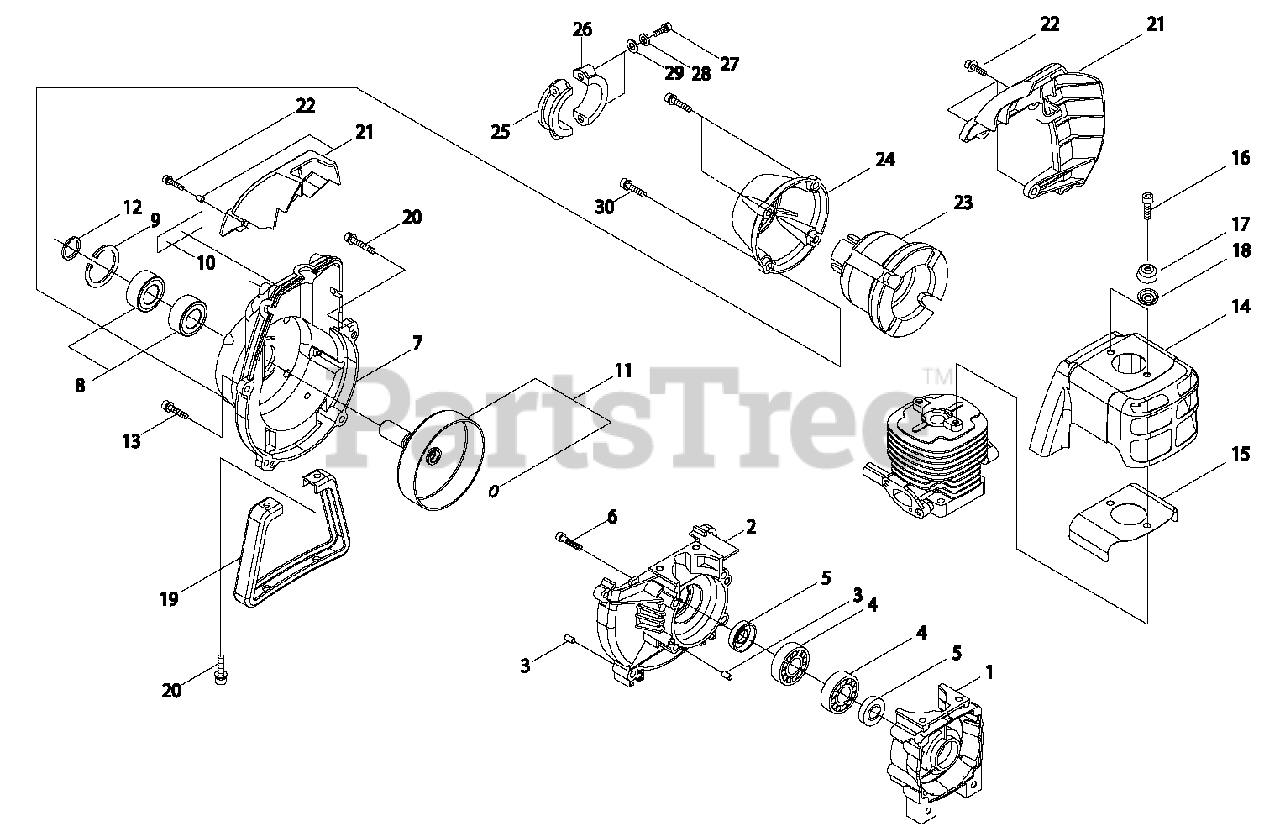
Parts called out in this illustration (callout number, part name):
1	CRANKCASE S
2	CRANKCASE M
3	PIN, LOCATING 5×10
4	BEARING, BALL 6202 C3
5	SEAL, OIL 16
6	BOLT 5×30
7	COVER, FAN
8	BEARING, BALL 6002 DDU
9	RING, SNAP Ø32
10	PLATE, NAME
11	DRUM, CLUTCH
12	RING, SNAP
13	BOLT M5×20
14	COVER, ENGINE
15	SHIELD, HEAT
16	BOLT M5×14
17	COVER
18	WASHER
19	STAND
20	BOLT M5×16
21	GUARD, TOP
22	BOLT M4×16
23	CUSHION, AV
24	CAP, CUSHION
25	CLAMP - A
26	CLAMP - B
27	BOLT 5×25
28	WASHER, SPRING 5
29	WASHER, FLAT 5.5×10×0.8
30	BOLT M5×20
